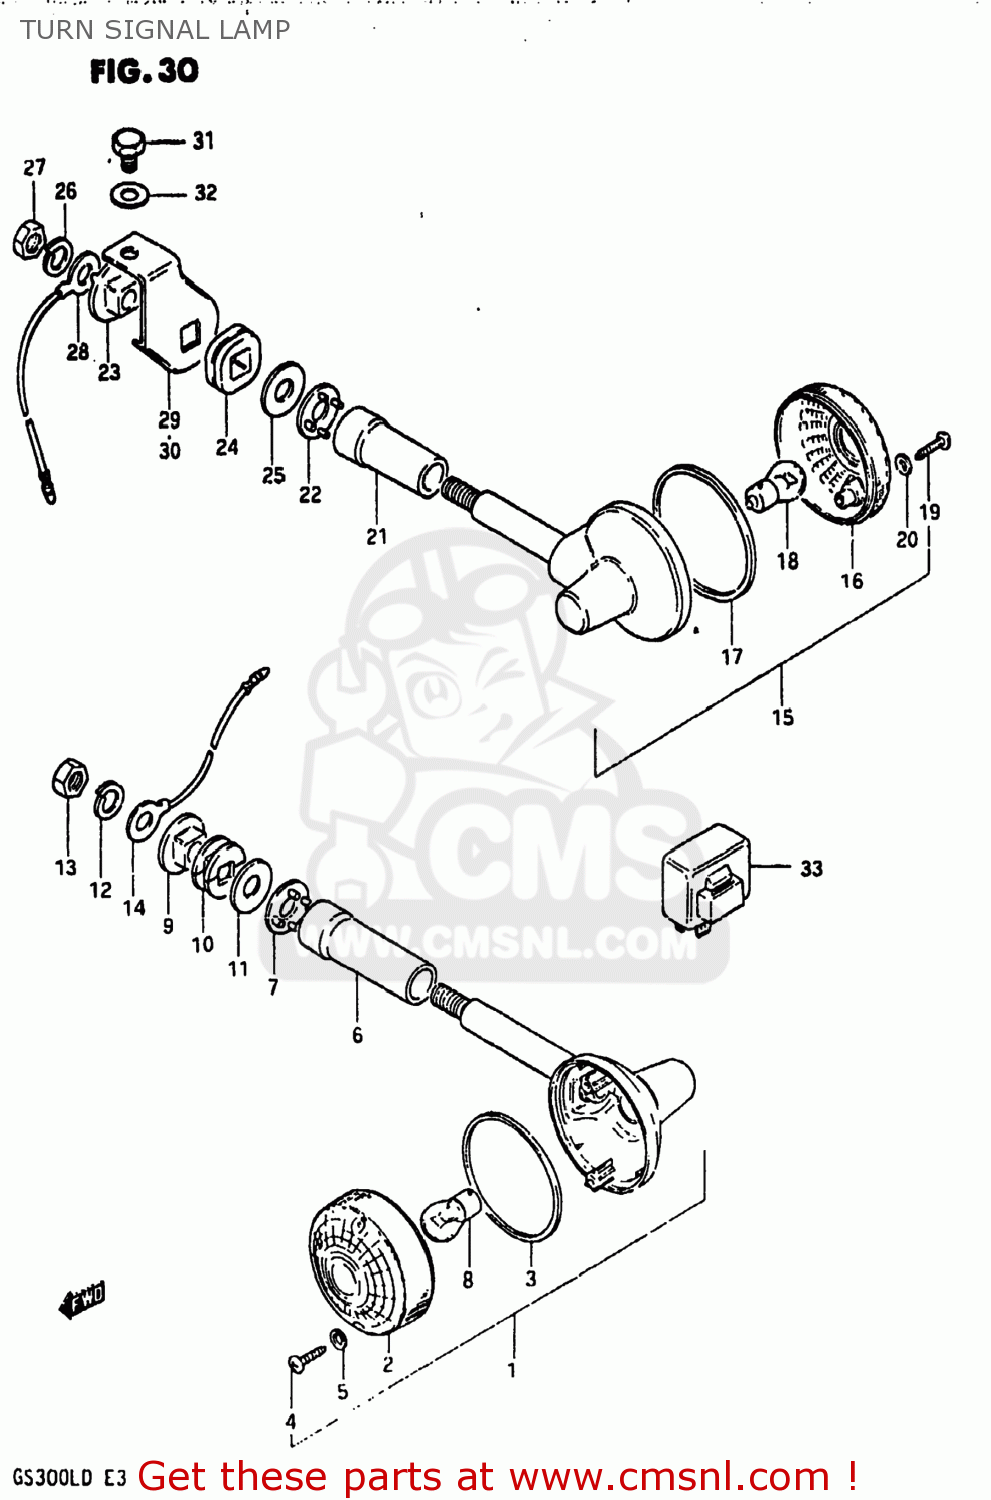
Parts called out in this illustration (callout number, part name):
1	LAMP ASSY,TURNSIGNAL
2	LENS
3	GASKET (NAS)
4	SCREW
5	GASKET (NAS)
6	COVER,STAY
7	SPACER
8	BULB(12V23W,STANLEY,A4577A)
9	SPACER
10	CUSHION
11	WASHER (10.5X30X2.3)
12	LOCK WASHER
13	NUT
14	LEAD WIRE,EARTH
15	LAMP ASSY,RR TURNSIGNAL
16	LENS
17	GASKET (NAS)
18	BULB(12V23W,STANLEY,A4577A)
19	SCREW
20	GASKET (NAS)
21	COVER
22	SPACER
23	SPACER
24	CUSHION
25	WASHER (10.5X30X2.3)
26	LOCK WASHER
27	NUT
28	LEAD WIRE,EARTH
29	BRACKET,RR TURNSIGNAL LAMP,R
30	BRACKET,REAR TURN SIGNAL
31	BOLT 8X12
32	WASHER
33	RELAY,TURN SIGNAL
